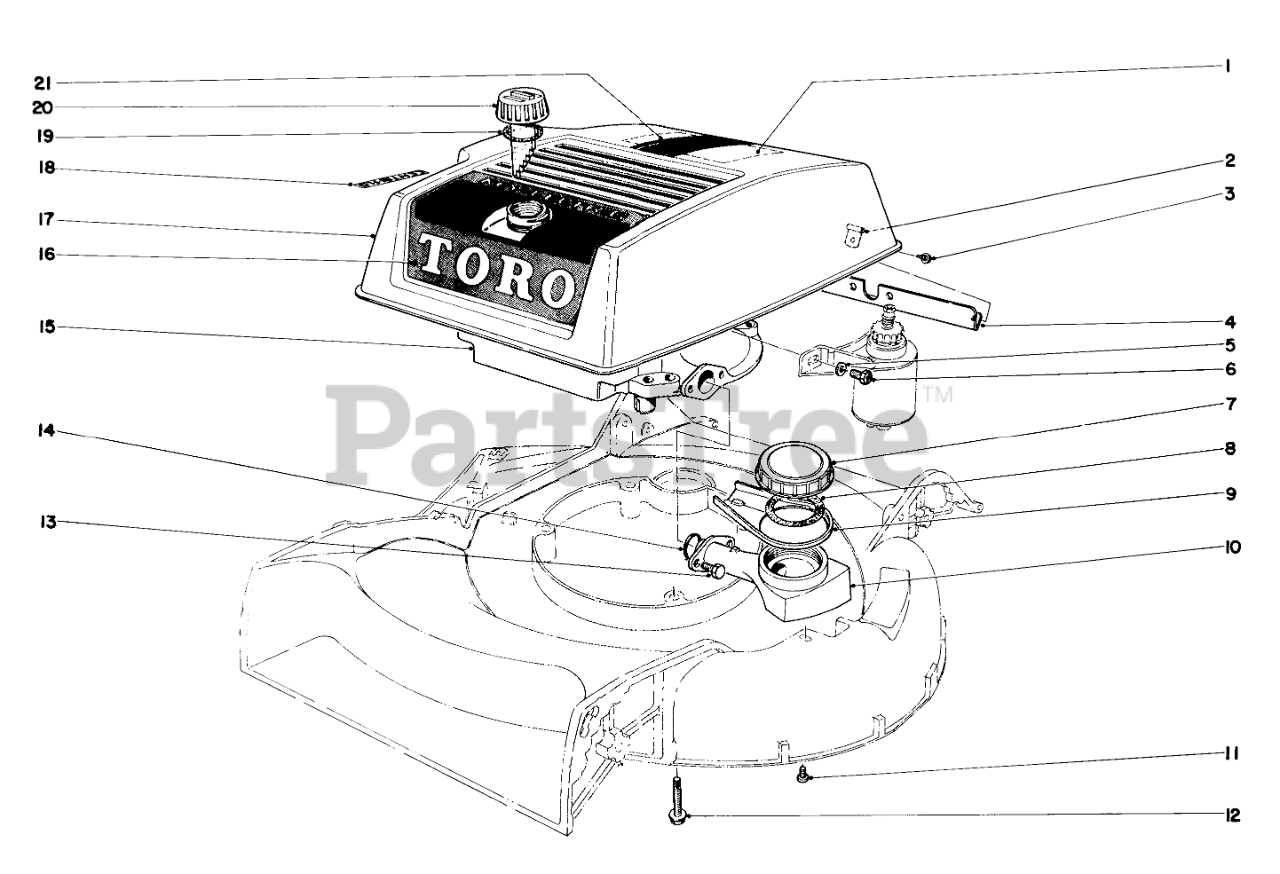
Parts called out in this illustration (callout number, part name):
1	Decal-Maintenance
2	Hinge
3	SCREW-HWHTF
4	Shroud Bracket
5	WASHER-FLAT
6	Screw
7	Oil Gauge Cap
8	VISUAL OILER GASKET
9	Spout
10	Oil Gauge
11	Screw
12	3/8-16 X 2-3/4 CAPSCR
13	Screw
14	O RING
15	Engine
16	Decal
17	Shroud
18	Decal, Air Cleaner
19	Gasket
20	Gas Cap
21	Decal
